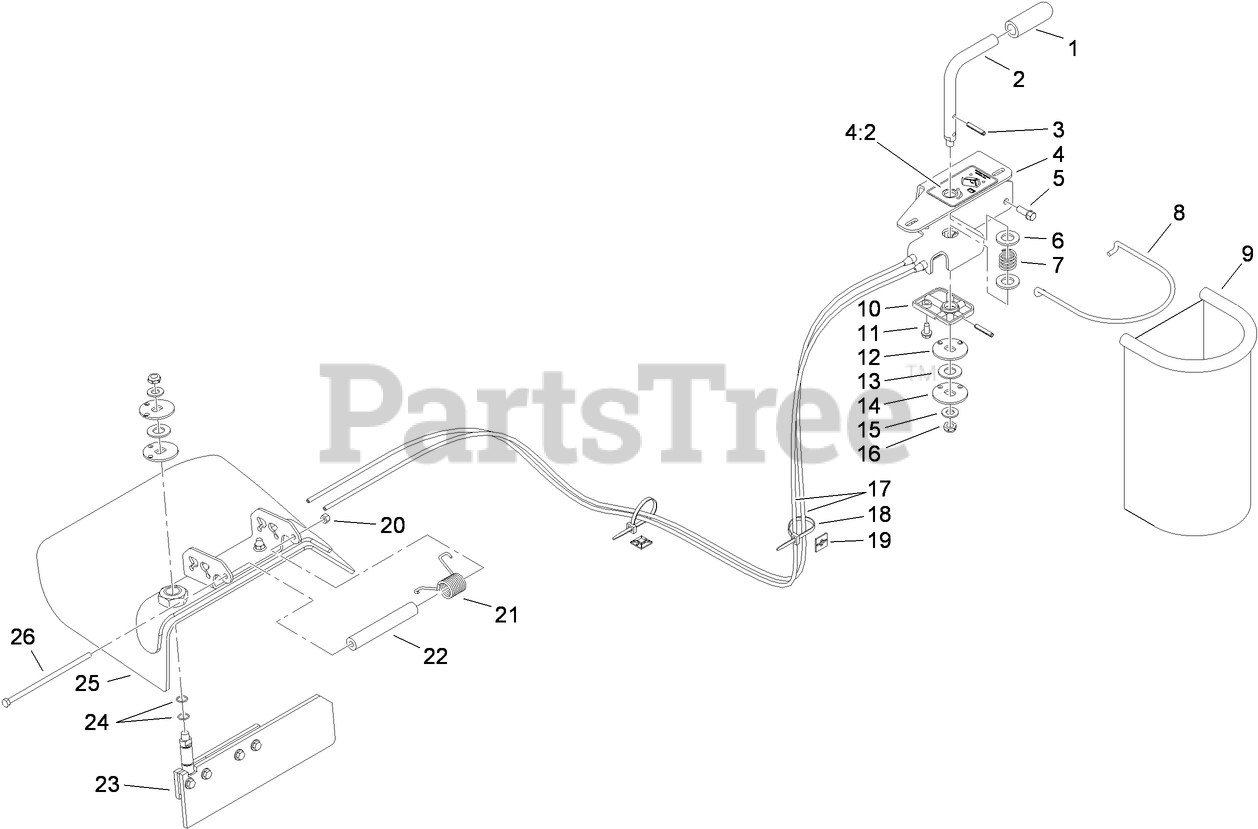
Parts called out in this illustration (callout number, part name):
2	HANDLE
3	PIN-ROLL
4	CONTROL BRACKET ASM
4:2	DECAL-GATE, CHUTE
5	SCREW-HWH
6	WASHER-FLAT
7	SPRING-COMPRESSION
8	ROD-BAG, TRASH
9	BAG-TRASH
10	BLOCK-DETENT
11	SCREW-HWHTF
12	PULLEY-TOP
13	PULLEY-MIDDLE
14	PULLEY-BOTTOM
15	WASHER-FLAT
16	NUT-LOCK, NI
18	TIE-CABLE
19	MOUNT-TIE, CABLE
20	NUT-LOCK, NI
21	SPRING-TORSION
22	SPACER
23	DOOR ASM
24	O-RING
25	DEFLECTOR ASM
26	SCREW-HH
